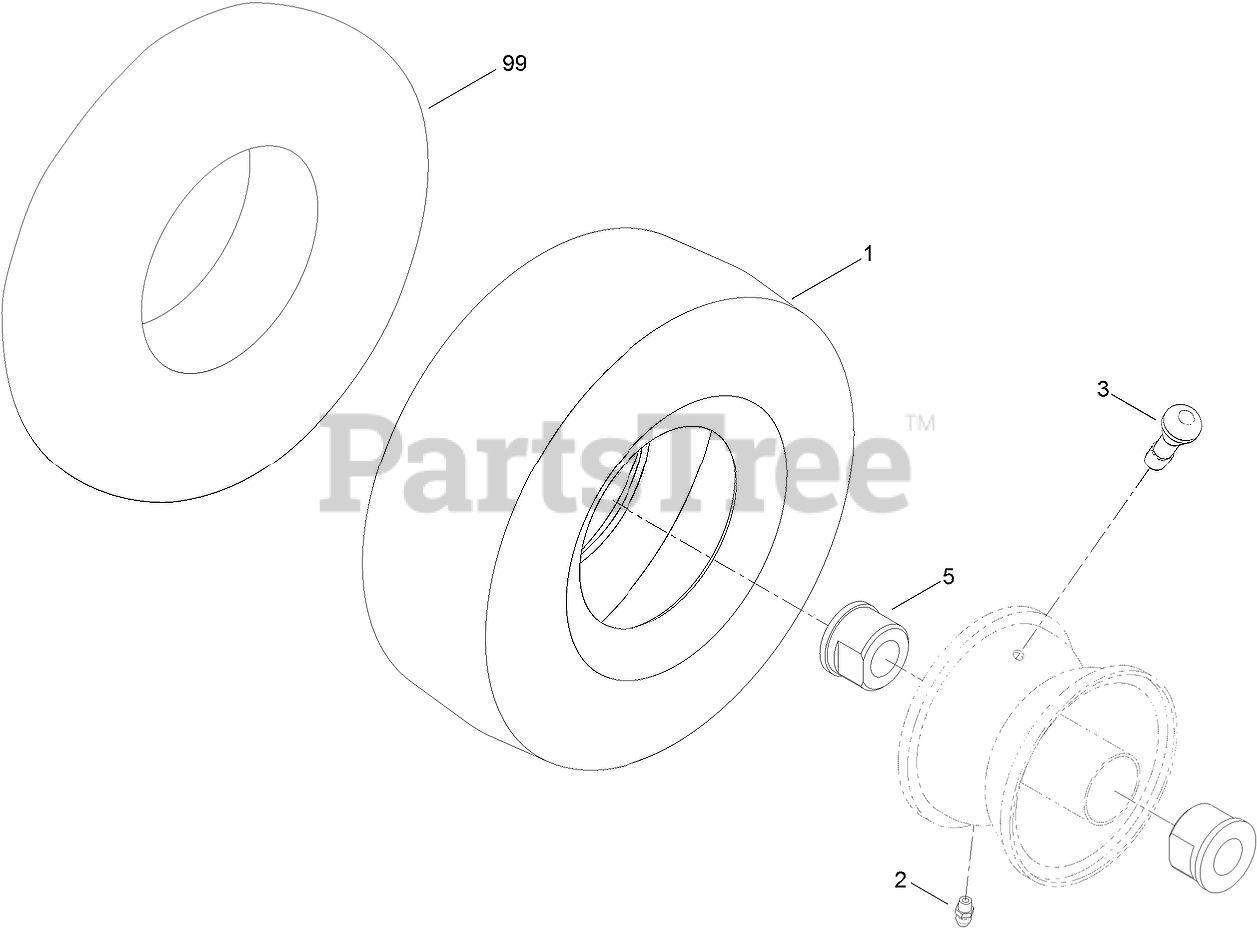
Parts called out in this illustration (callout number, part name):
1	TIRE-SMOOTH (Kenda)
2	FITTING-GREASE
3	STEM-VALVE
5	BUSHING-FLANGE
99	TUBE-INNER (W/VALVE)
